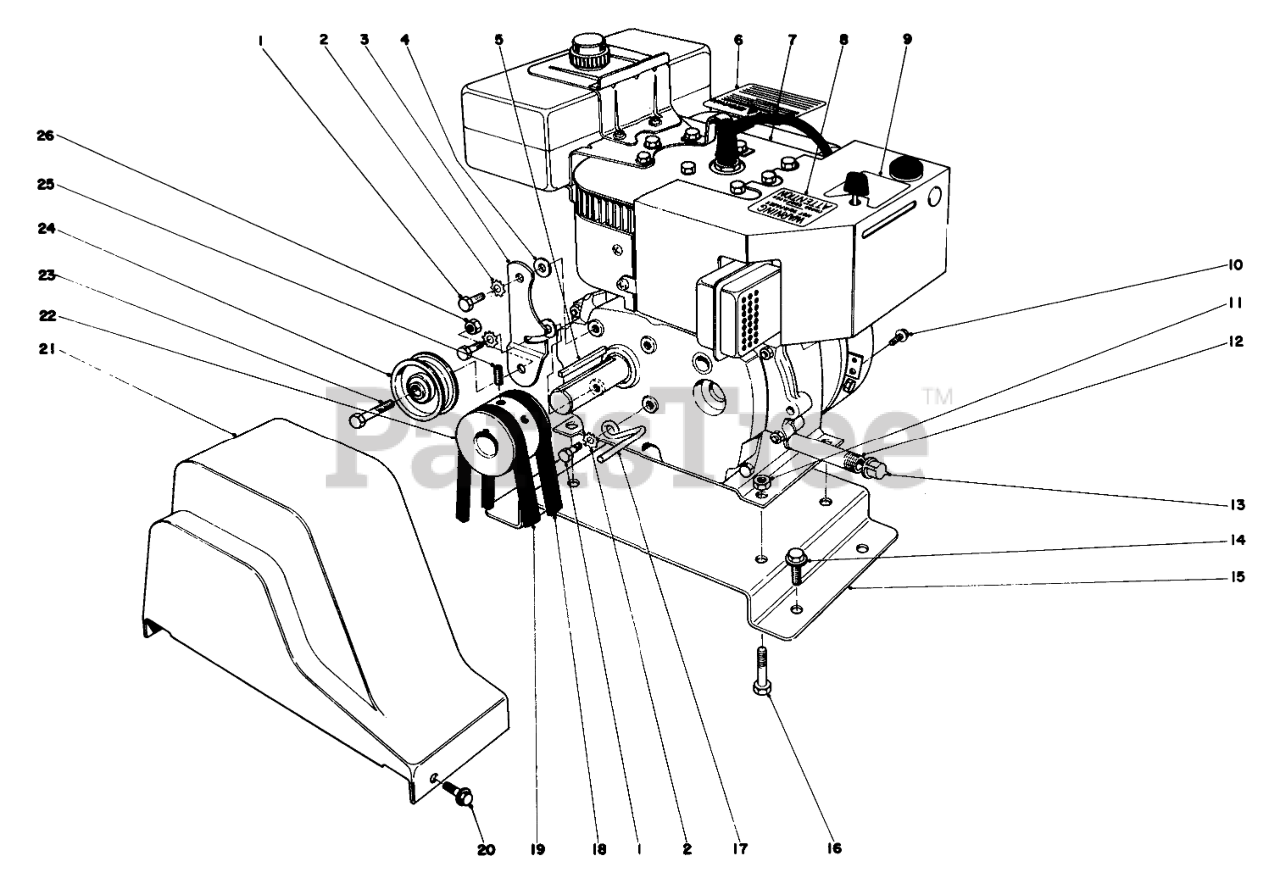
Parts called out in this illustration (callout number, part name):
1	SCREW-HH
2	WASHER-LOCK
3	ENGINE IDLER ARM
4	WASHER-FLAT
6	CAUTION DECAL
7	Engine
8	Decal Hot Surface Warning
9	Decal-Choke & Primer
10	SCREW
11	NUT-LOCK, NI
12	NIPPLE-PIPE
13	CAP-PIPE
14	SCREW-HHFTF
15	ENG MTG PLATE R
16	SCREW-HH
17	BELT RETAINER
18	V-BELT
19	V-BELT
20	SCREW-HWH
21	BELT GUARD
22	Pulley
23	SCREW-HH
24	Idler Pulley
25	Screw-Set
26	NUT-HEX
